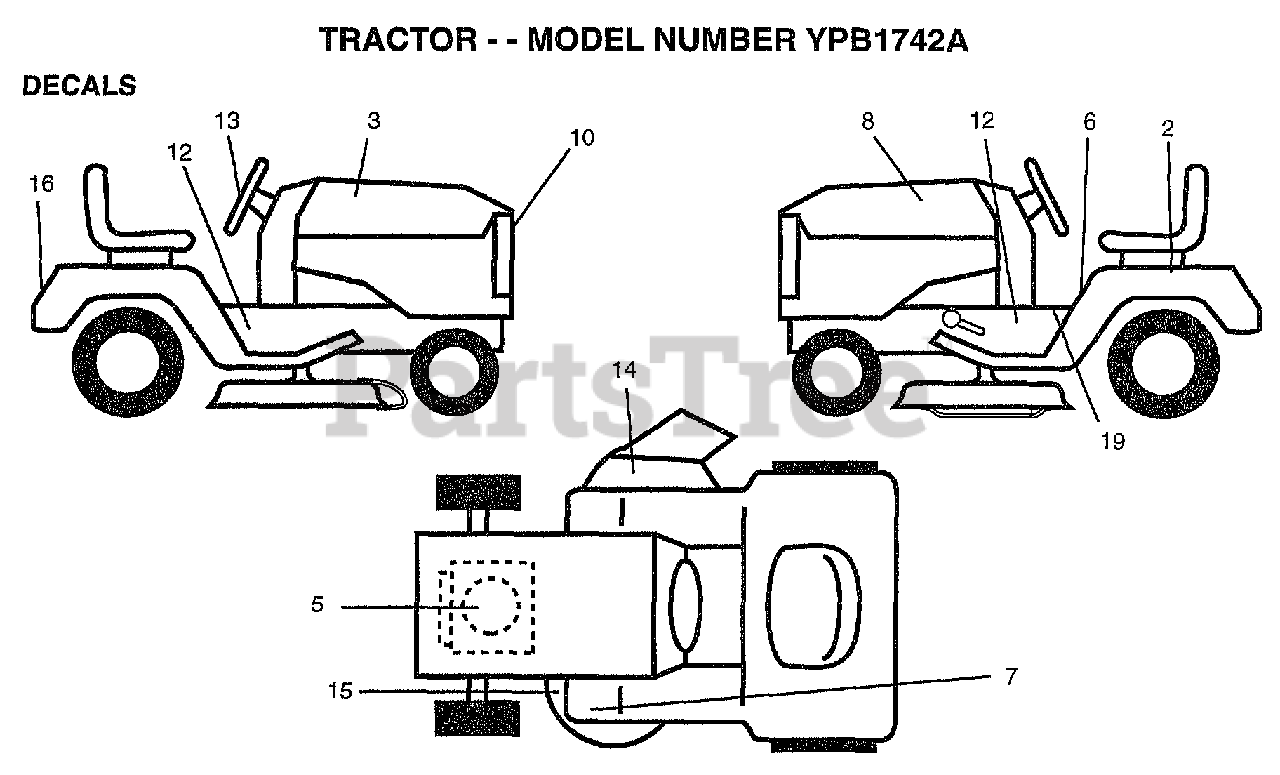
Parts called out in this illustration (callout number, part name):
2	DECAL.BATRY.3-3908
3	DECAL
5	DECAL.ENGINE.HP.B&S
6	DECAL.CAUT.ENG/FR
7	DECAL T
8	DECAL
12	DECAL CHASSIS
13	DECAL INS STRG WH
14	"DECAL, WARNING"
15	"DECAL-SCHEM,BELT"
16	DECAL FENDER
19	"DECAL.OPER,SDL"
